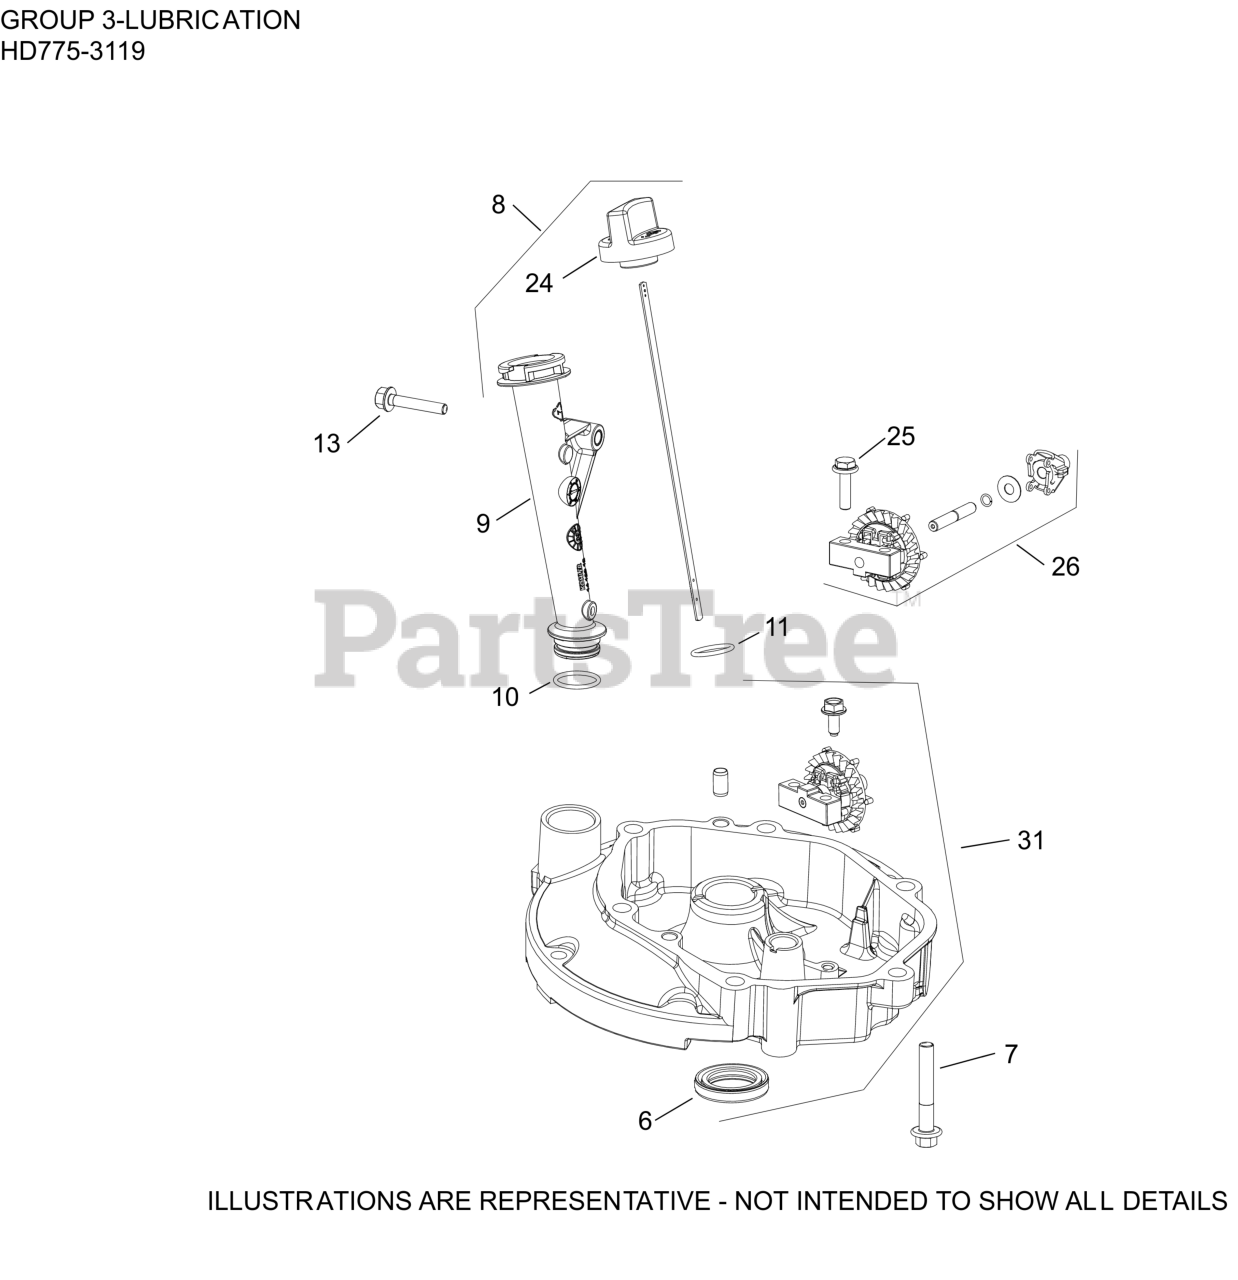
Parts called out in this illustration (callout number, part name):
7	SCREW, HEX FLANGE (M8)-USE 25 086 456-S
8	KIT, DIPSTICK AND TUBE
9	TUBE, OIL FILL
13	SCREW, HEX FLANGE (M6)-(#25086435S)
24	CAP, DIPSTICK-USE 14 227 23-S
25	SCREW, M6 X 22
26	GOVERNOR GEAR, ASSEMBLY
31	KIT, OIL PAN
